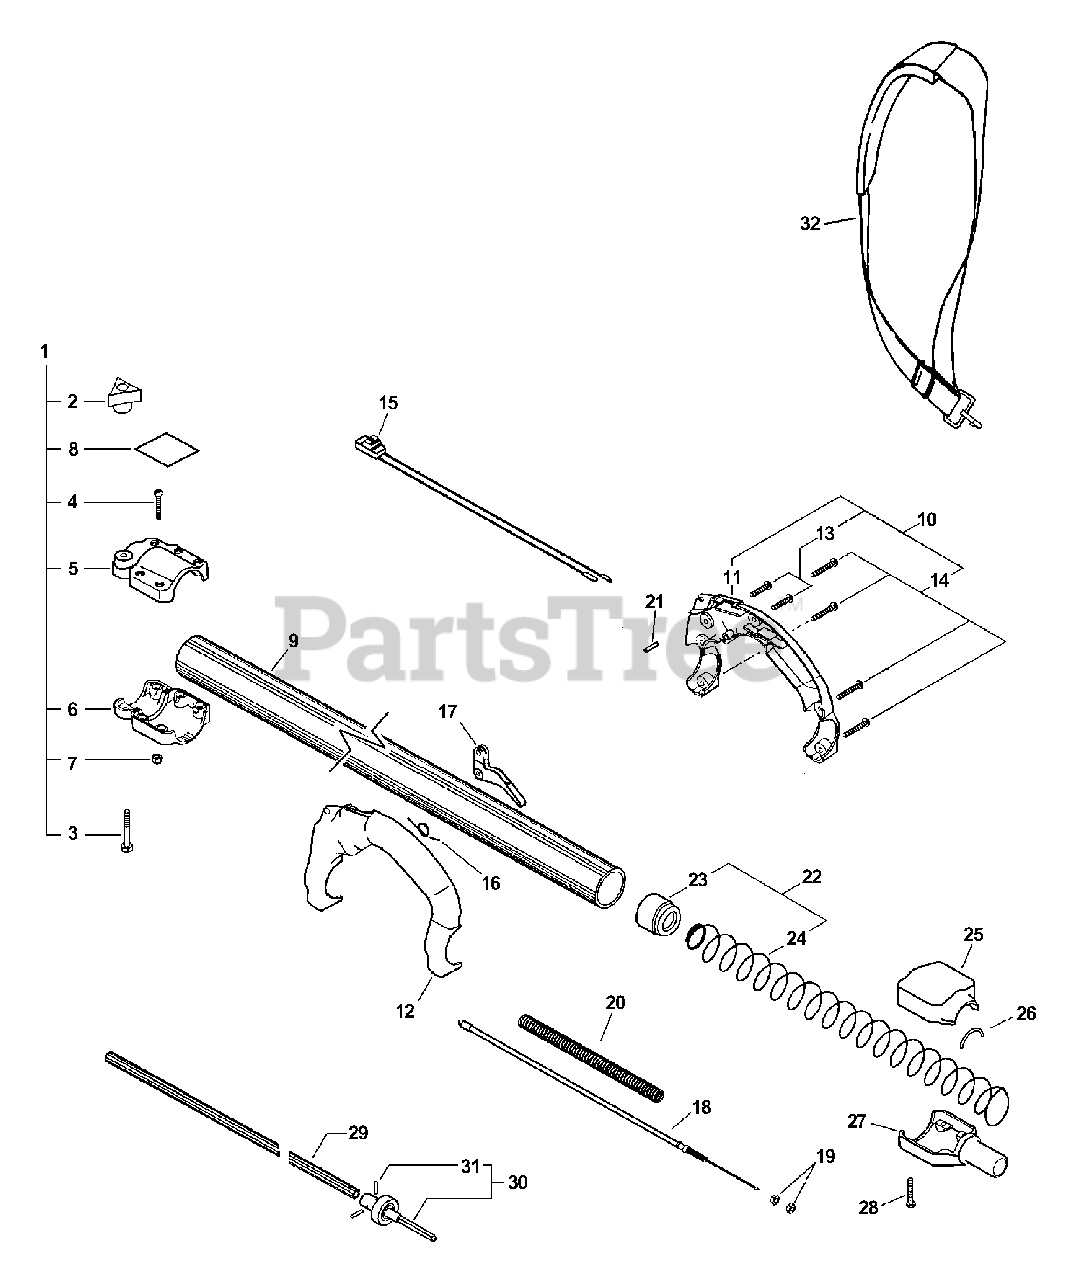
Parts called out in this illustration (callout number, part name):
1	CLAMP ASSY
2	THUMBSCREW
3	SCREW
4	SCREW, TORX 10-24 UNC 1-1/4
5	COLLAR, UPPER
6	COLLAR, LOWER
7	NUT, LOCK 10-24 UNC
8	LABEL - CAUTION
9	PIPE, MAIN 1.5 ID×60" L
10	REAR HANDLE ASSY
11	HANDLE, REAR - RIGHT
12	HANDLE, REAR - LEFT
13	SCREW, TORX
14	SCREW, TORX 10-24 UNC 1-1/4
15	SWITCH ASSY, ON-OFF
16	SPRING, TORSION
17	TRIGGER, THROTTLE
18	CABLE, THROTTLE
20	TUBE, FLEXIBLE
21	PIN, LOCATING 0.17 OD×0.75 L
22	BUSHING ASSY, FLOATING
23	BUSHING, FLOATING
24	SPRING, COMPRESSION
25	CAP, MAIN PIPE
27	COUPLING, MAIN PIPE
28	SCREW, TORX 10-24 UNC 1-1/4
29	DRIVESHAFT
30	SHAFT CONNECTOR KIT
31	PIN 0.098"×0.687"
32	STRAP ASSY, SHOULDER
